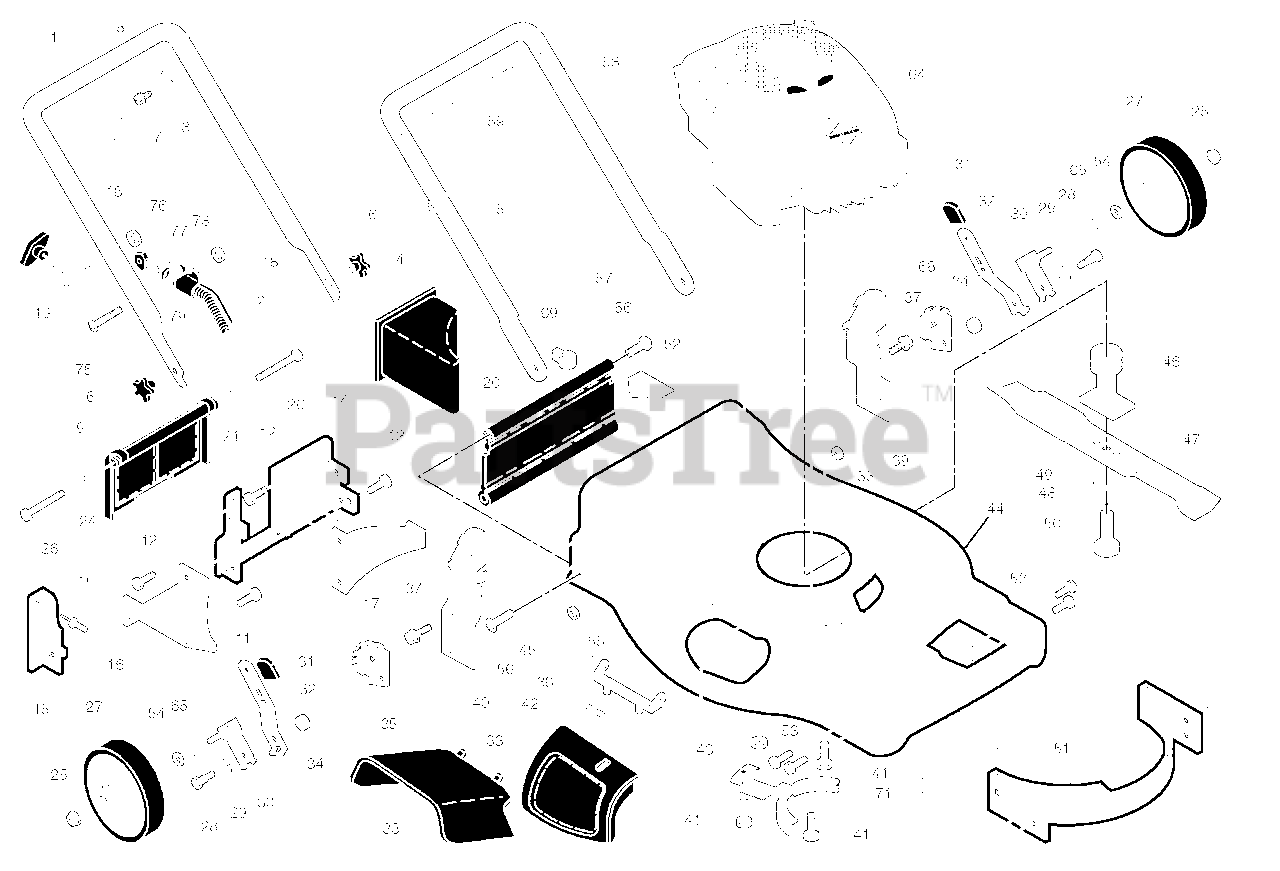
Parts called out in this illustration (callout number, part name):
1	Upper Handle
2	Cable, Operator Presence
3	Bracket, Upstop
4	Mulcher Plug
5	Wire Tie
6	Handle Knob
7	Screw
8	Control Bar
9	Rear Door Assembly
10	Pop Rivet
11	Screw, Self-Tapping 10-24 x 5/8
12	Screw, Hex Hex Head, Sems 1/4-20 x 1/2
14	Back Plate
15	Side Baffle
16	Discharge Baffle
17	Rear Baffle
18	Keps Locknut 1/4-20
19	Rope Guide
20	Rear Skirt
21	Spring, Rear Door, LH
24	Spring, Rear Door, RH
25	Nut, Hex, Flanged
26	Bolt, Rear Door
27	Wheel & Tire Assembly, Rear
28	Bolt, Shoulder 3/8-16 x 1
29	Washer, Curved, Cylindrical
30	Axle Arm Assembly
31	Selector Knob
32	Selector Spring
33	Mulcher Door
34	Spacer
35	Wheel Adjusting Bracket, RH
36	Hinge Bracket Assembly
37	Screw
38	Discharge Deflector
39	Handle Bracket Assembly, LH
40	Handle Bracket Assembly, RH
41	Screw, Hex Head, Threaded, Rolled 3/8-16 x 1-1/8
42	Spring, Torsion
43	Nut, Hex, Nylock
44	Kit, Mower Housing
45	Rod, Hinge
46	Blade Adapter / Pulley
47	Blade, 22"
48	Washer, Helical
49	Washer, Hardened
50	Screw, Machine, Hex Head 3/8-24 x 1-3/8 Grade 8
51	Kit, Front Baffle
52	Danger Decal
53	Screw, Serrated, TT 1/4-20
54	Washer, Flat
55	Locknut, Hex 3/8-16
56	Hinge Screw 1/4-20 x 1-1/4
57	Hairpin Cotter
58	Lower Handle
59	Handle Bolt
65	O-Ring
68	Wheel Adjusting Bracket, LH
69	Clip, Cable
71	Belt Keeper
75	Screw
76	Key
77	Nut, Cap
78	Key Start Switch
79	Wiring Harness
79	Operator's Manual, English
79	Operator's Manual, French
79	Repair Parts Manual
